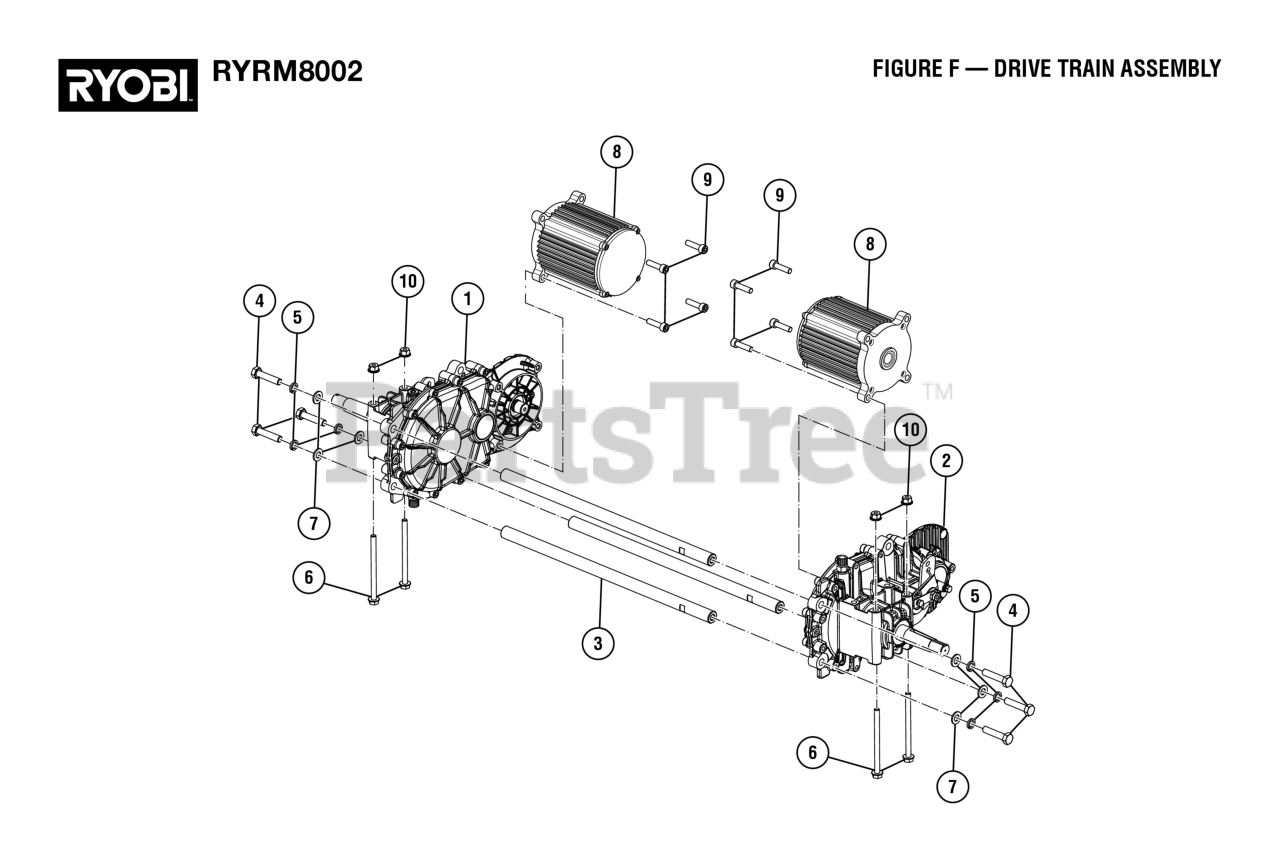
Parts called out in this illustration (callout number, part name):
1	GEARBOX, LEFT
2	GEARBOX, RIGHT
4	Bolt (M10 x 45 mm, Hex Hd.)
5	Lock Washer (M10)
6	Flange Bolt (M8 x 110 mm, Hex Hd.)
7	Washer (OD20 x ID10.5 x 2t)
8	80V Drive Motor
9	Screw (M8 x 30 mm, Soc. Hd.)
10	Flange Nut (M8) (For Drive Motor Controller V)
